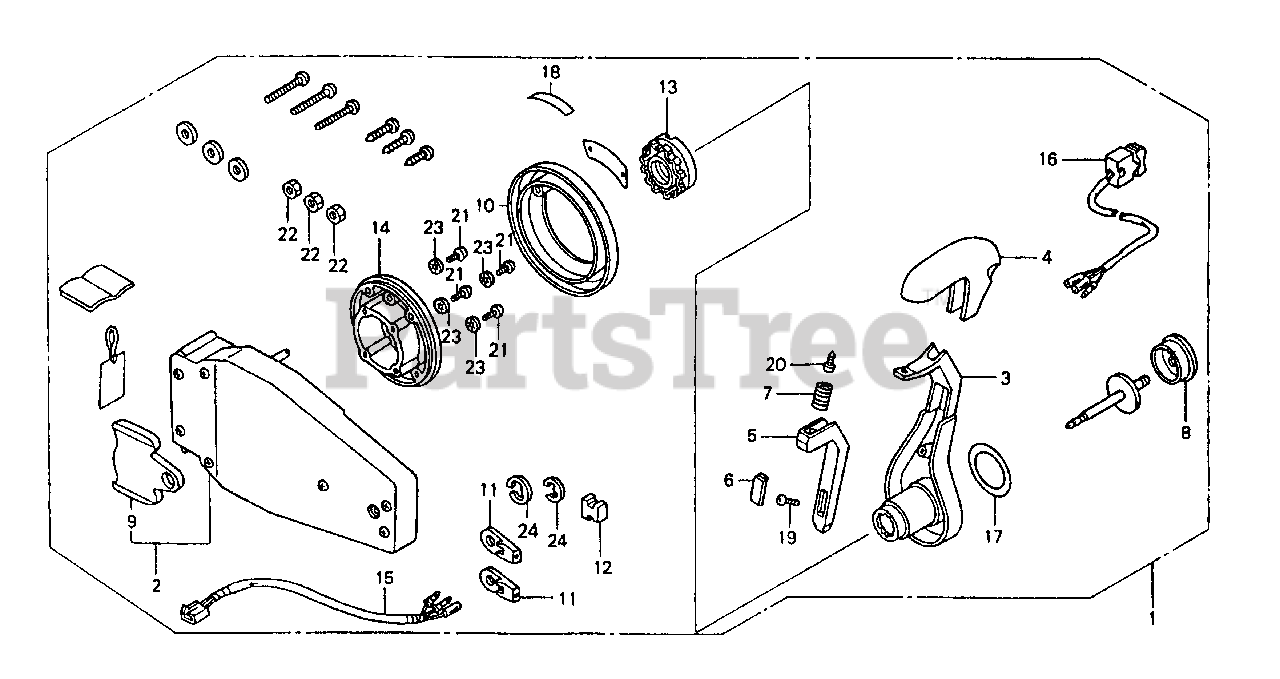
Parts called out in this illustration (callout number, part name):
1	BOX KIT, L. REMOTE CONTROL
2	HOUSING ASSY., L. (INNER)
3	HANDLE, REMOTE CONTROL
4	COVER, GRIP
5	ARM, NEUTRAL LOCK
6	COVER, LOCK ARM
7	SPRING, NEUTRAL LOCK ARM
8	BUTTON, THROTTLE
9	PLATE, DWELL
10	COVER ASSY.
11	CABLE, TERMINAL
12	SPACER, CABLE CLAMP
13	HOLDER, NEUTRAL LOCK
15	SUB-HARNESS C ASSY., POWER
16	SWITCH ASSY., POWER TRIM-TILT
17	MARK, HANDLE (FLUSH MOUNT)
18	MARK, FLUSH MOUNT
19	SCREW, TRUSS (4X12)
20	SCREW, PAN (5X10)
21	SCREW, PAN (5X30)
22	NUT, HEX. (6MM)
23	WASHER, LOCK (5MM)
24	E-RING (6MM)
